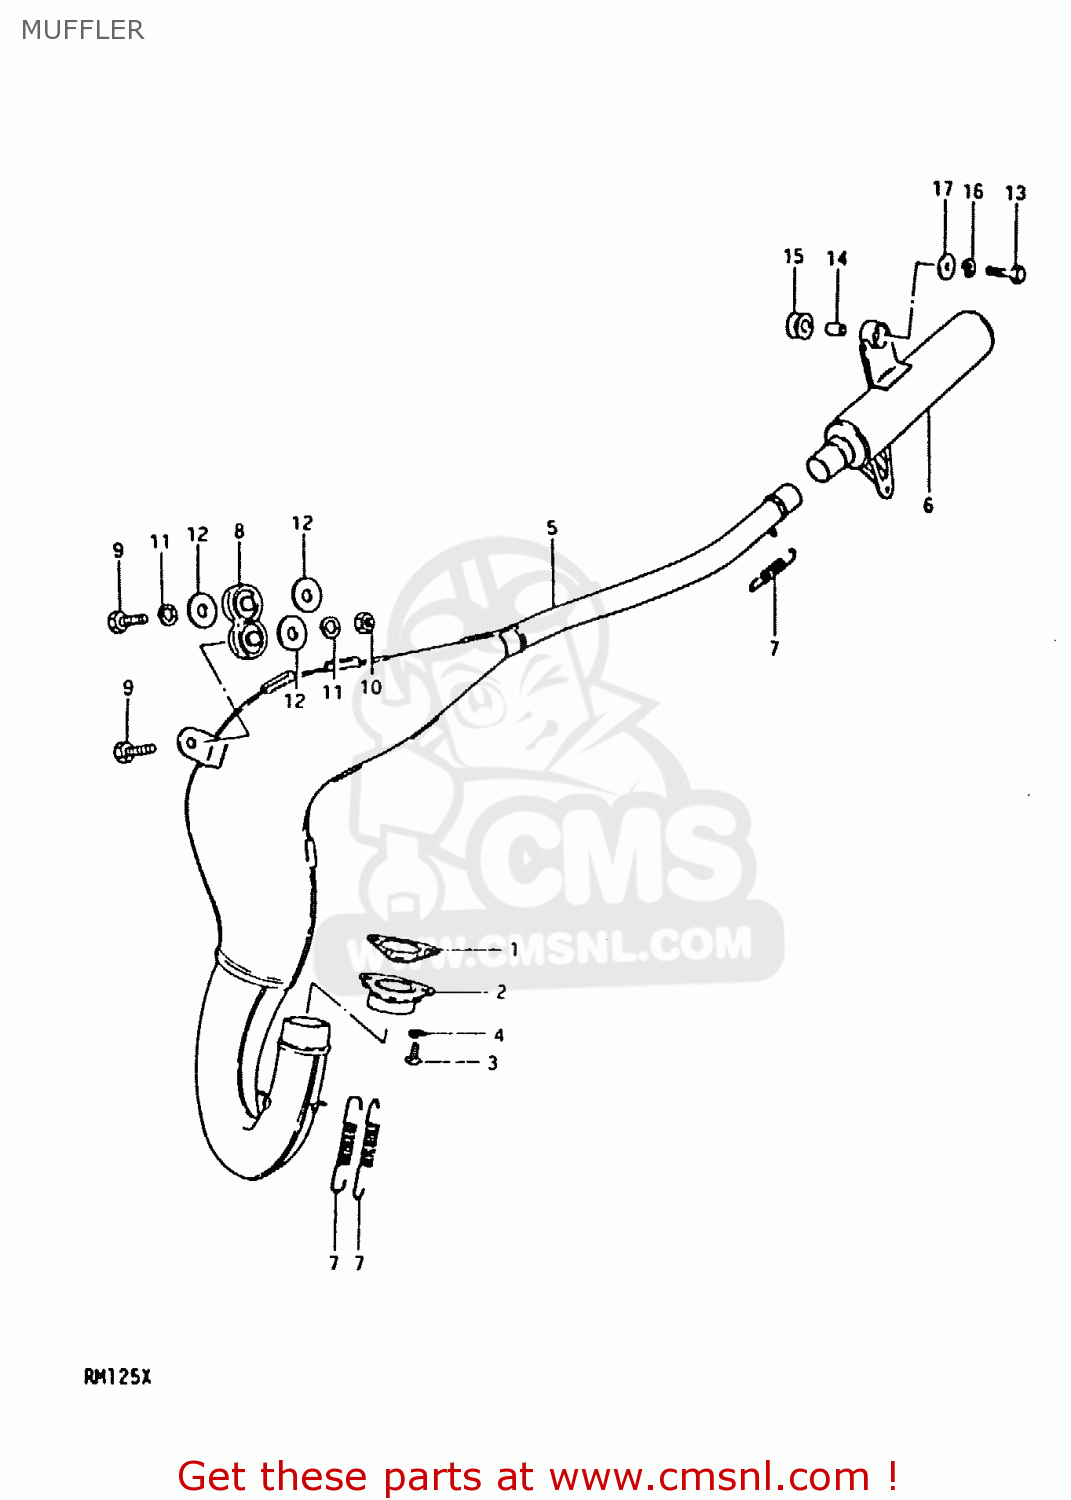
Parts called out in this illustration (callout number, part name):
1	GASKET,EXHAUST PIPE (MCA)
2	FLANGE,EXHAUST PIPE
3	SCREW
4	LOCK WASHER
5	BODY,MUFFLER
6	BODY,MUFFLER
7	SPRING
8	DAMPER,MUFFLER
9	BOLT(8X32)
10	NUT 8MM
11	LOCK WASHER
12	WASHER
13	BOLT(8X32)
14	SPACER (8.2X12X17)
15	CUSHION
16	LOCK WASHER
17	WASHER (8.5X29X1.6)
